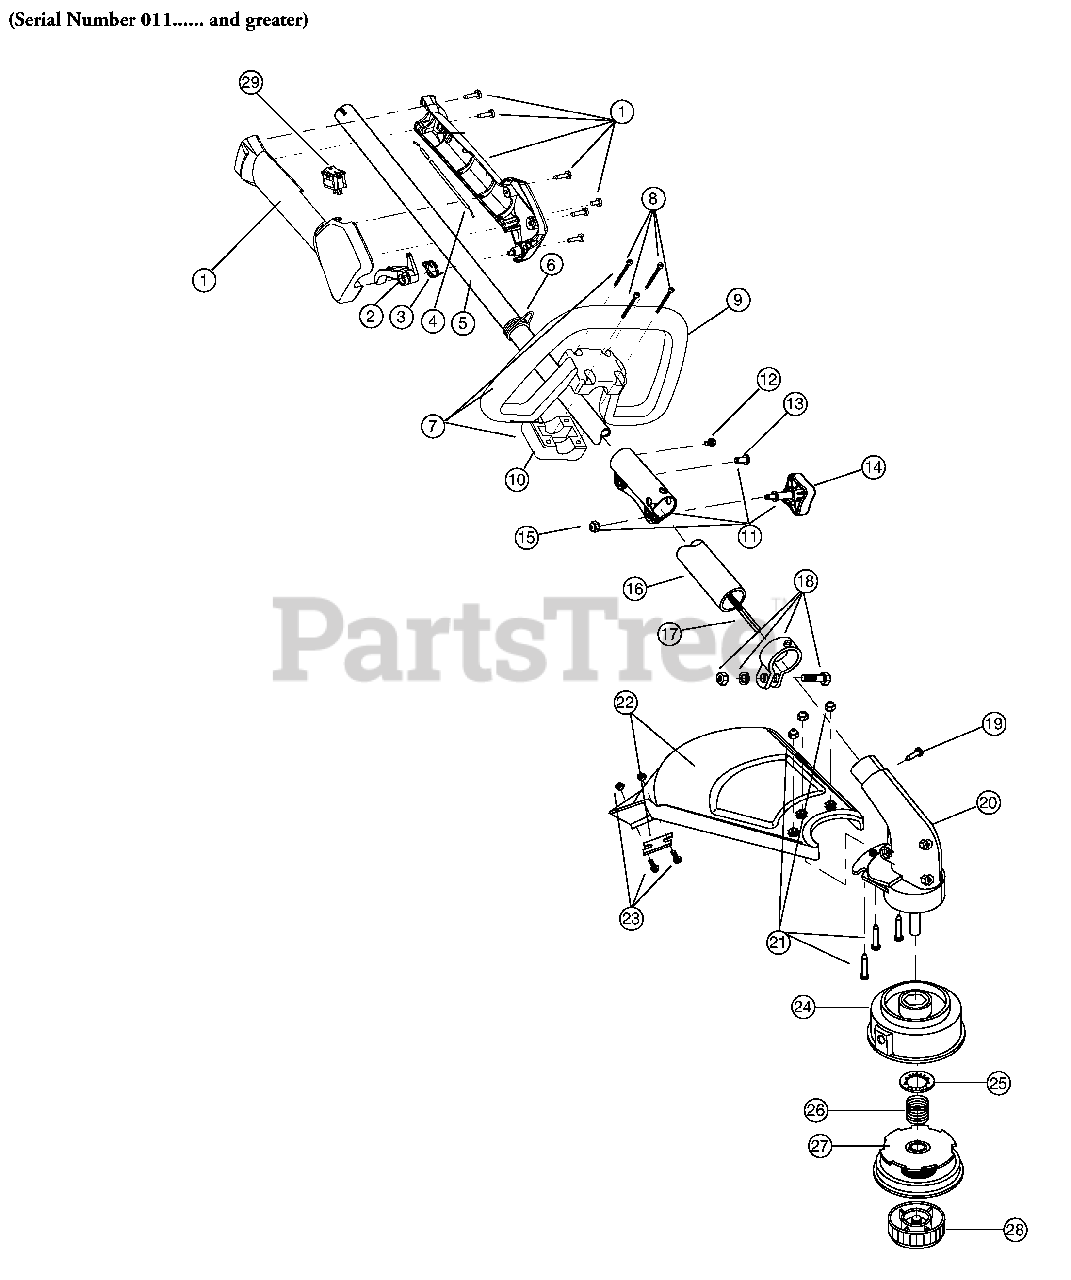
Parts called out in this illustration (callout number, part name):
1	Throttle Housing and Trigger Assembly
2	Throttle Trigger
3	Throttle Trigger Spring
4	Throttle Cable Assembly
5	Upper Drive Shaft Housing Assembly
6	Harness Clip
7	Deluxe D-Handle Assembly
9	Deluxe D-Handle
10	Bottom Clamp
11	EZ-Link (tm) Coupler
14	Adjustment Knob
15	Knob Retaining Bolt
16	Lower Drive Shaft Housing Assembly
17	Lower Flexible Drive Shaft
18	Lower Clamp Assembly
19	Anti-Rotation Screw
20	Gear Box Assembly
21	Shield Mounting Hardware
22	Shield and Blade Assembly
23	Blade Assembly
24	Outer Spool and Eyelet Assembly
27	Inner Reel
28	Bunp Head Knob Assembly
